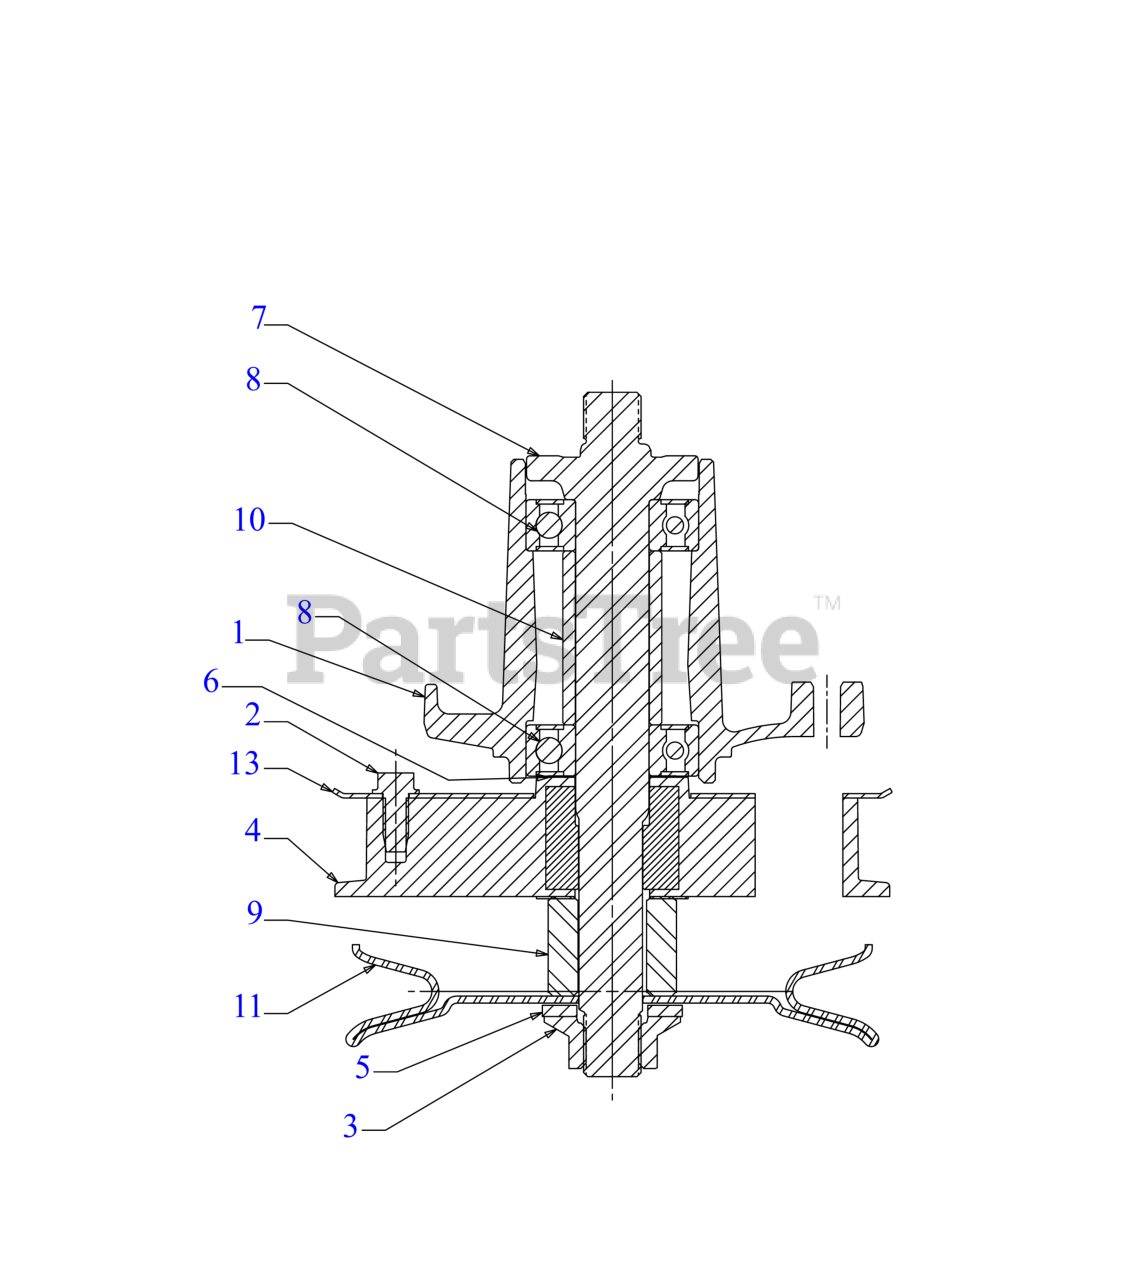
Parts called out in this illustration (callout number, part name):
1	SPINDLE HOUSING
2	SCREW 1/4-10:.625
3	FLANGE NUT 5/8-18
4	TIMING PULLEY 56T 11T SPLN
5	FLAT WASHER
6	THRUST WASHER .793X1.368X
7	SPINDLE SHAFT 6.65
8	BALL BEARING
9	DECK SPINDLE SPACER
10	SPACER- .792 x 1.060 x 1.860
11	DECK PULLEY
13	TIMING PULLEY PLATE
